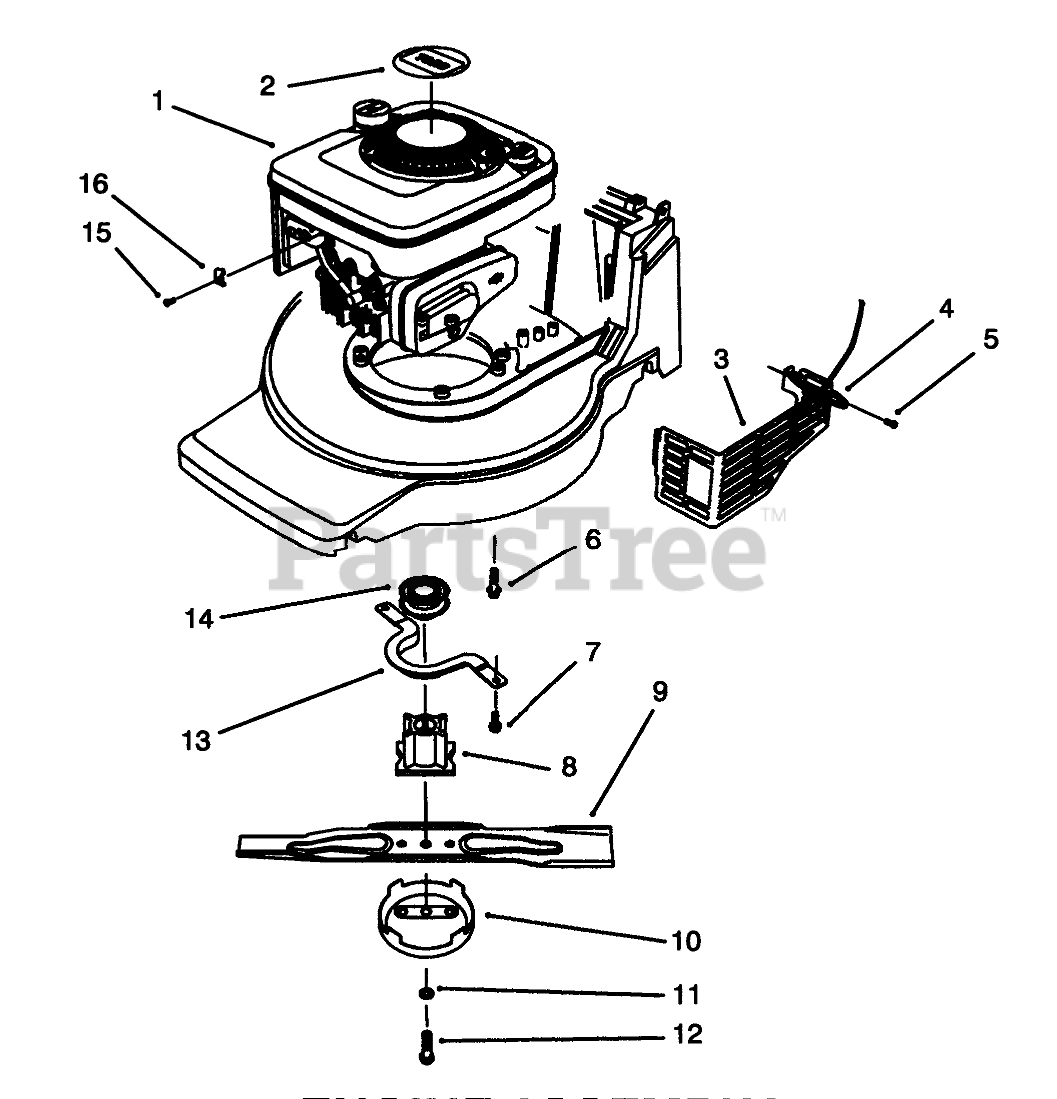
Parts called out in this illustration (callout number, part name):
1	Engine-B&S Quantum
2	DECAL - RECOIL
3	SHIELD-MUFFLER
4	TIE-CABLE
5	SCREW-HWH
6	SCREW-HWH
7	SCREW-HWH
8	BLADE RETAINER - 25 MM
9	Blade-48cm
10	CUP-SCALP, ANTI
11	WASHER-LOCK
12	BOLT-BLADE
13	Guide-Belt
14	PULLEY-DRIVE, ZONE START
15	CLAMP SCREW F/W ENGINE
16	CLAMP-CASING
